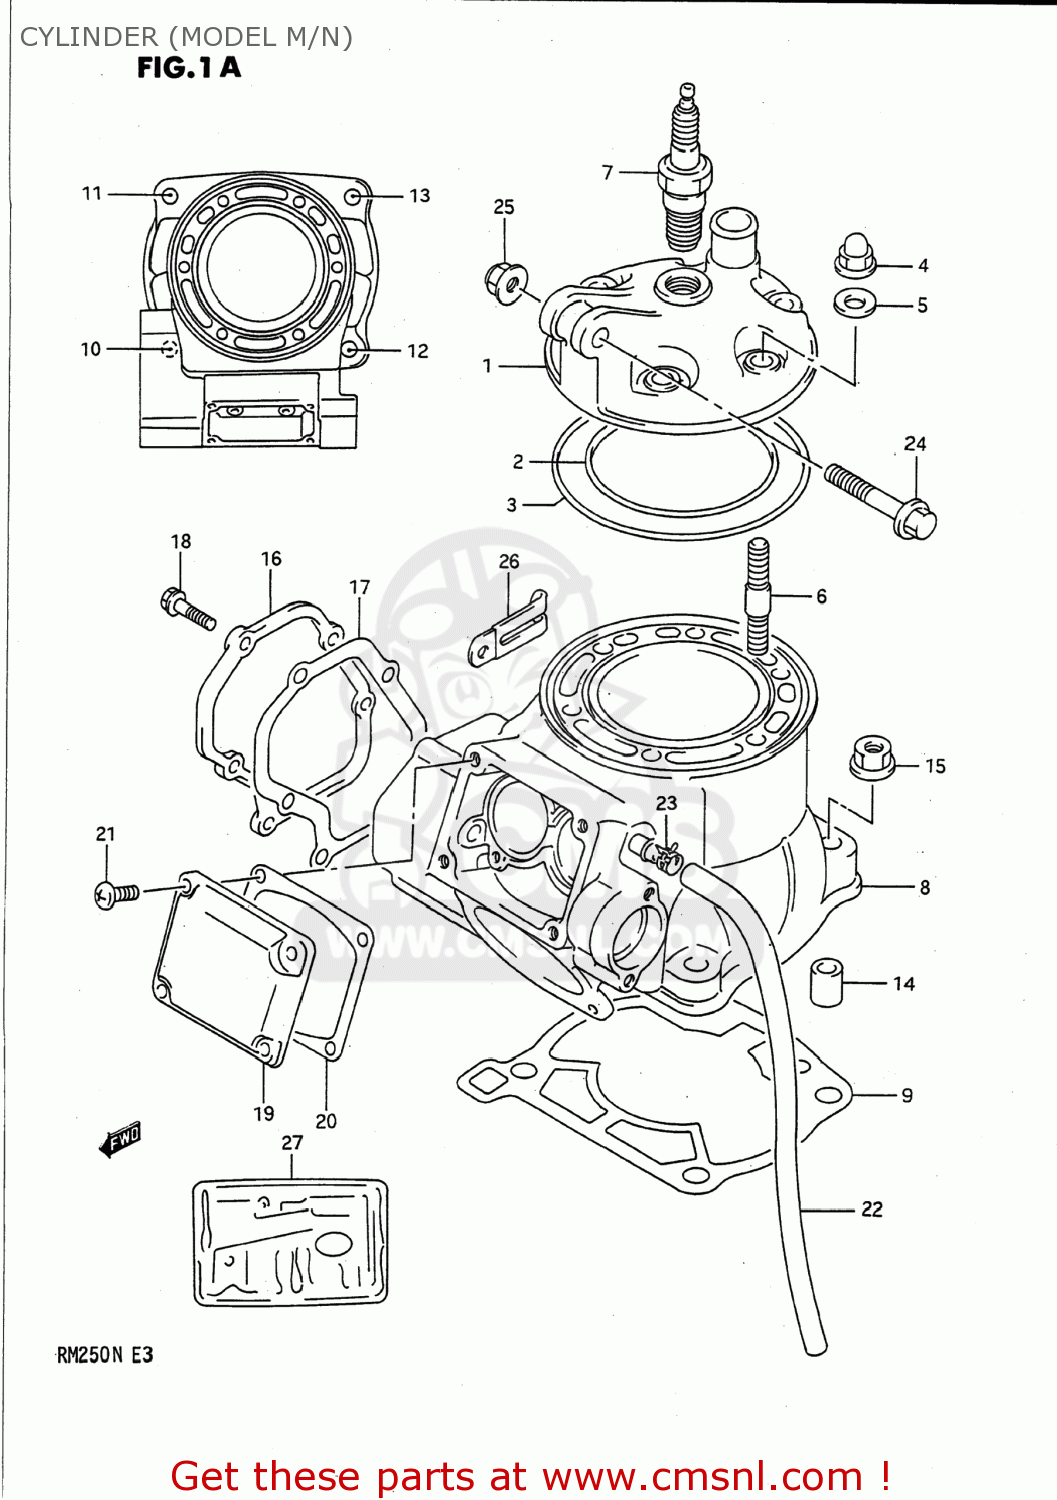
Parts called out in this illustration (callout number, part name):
1	HEAD,CYLINDER
2	O RING,CYLINDER HEAD NO.1
3	O RING,CYLINDER HEAD NO.2
4	NUT
5	GASKET(8.5X17X2.3) (NAS)
6	BOLT,STUD
7	PLUG,SPARK(R4118S-8)
8	CYLINDER
9	GASKET,CYLINDER (NAS)
10	STUD 10X30
11	STUD BOLT
12	STUD BOLT (L:40)
13	STUD BOLT (L:45)
14	PIN
15	NUT
16	COVER,CYLINDER NO.1
17	GASKET,CYLINDER COVER (NAS)
18	BOLT
19	COVER,CYLINDER NO.2
20	GASKET,CYLINDER COVER (NAS)
21	SCREW
22	HOSE
23	CLAMP
24	BOLT(8X45)
25	NUT
26	CLAMP L:35
27	GASKET SET
